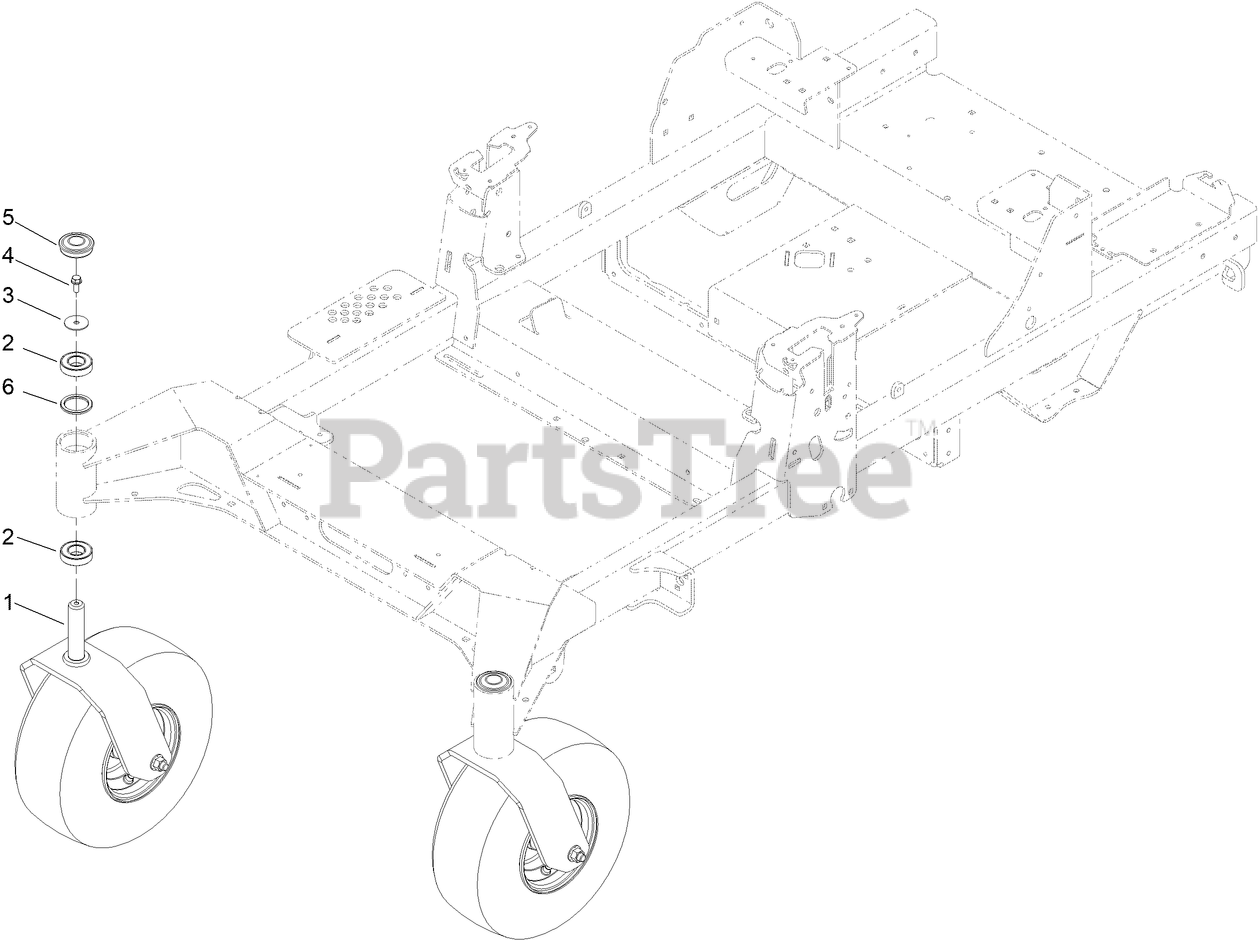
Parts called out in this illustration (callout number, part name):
1	ASM, FRONT CASTER W/ FORK
2	BEARING-BALL
3	WASHER-FLAT
4	SCREW-HHF
5	CAP,GREASE
6	SPACER-BEARING
